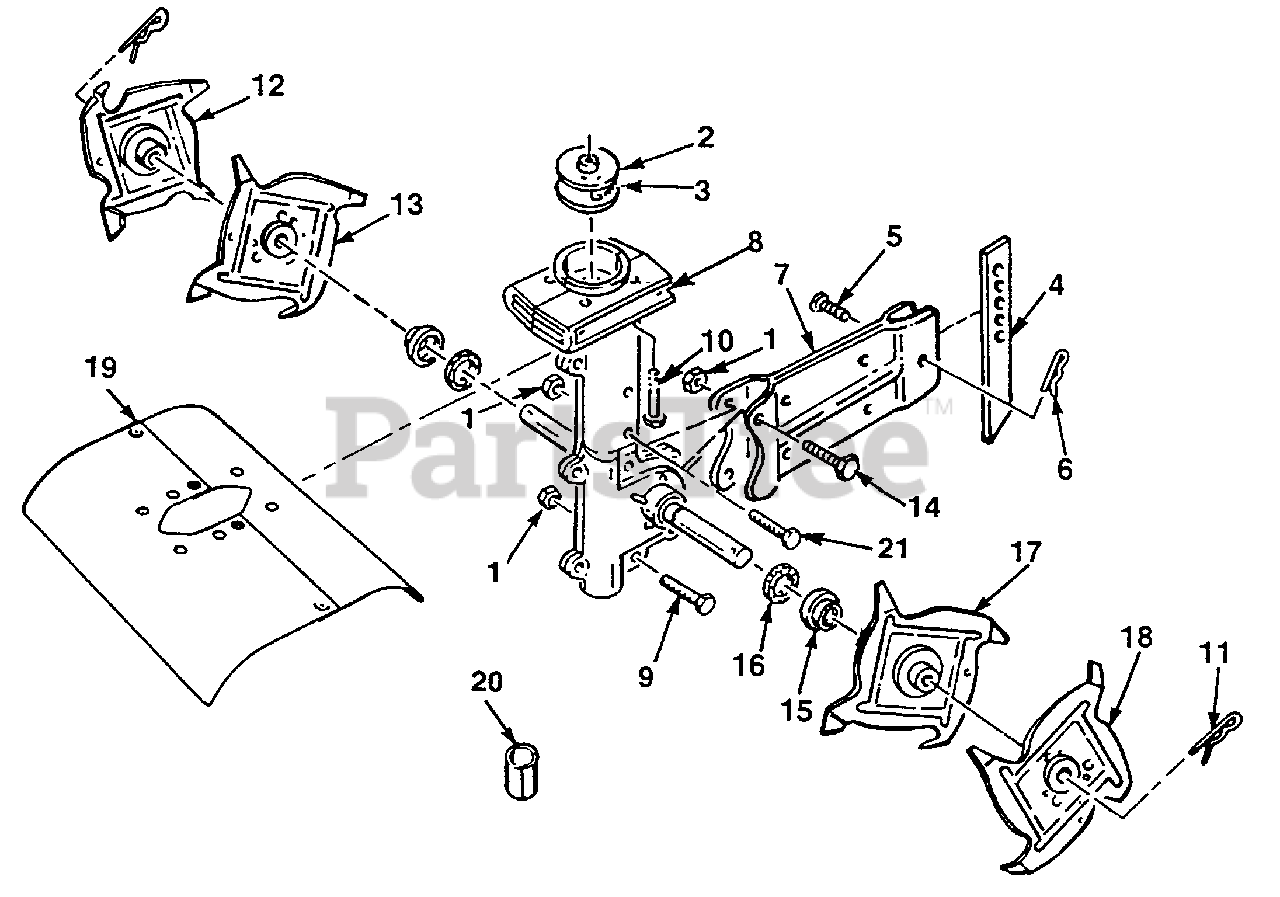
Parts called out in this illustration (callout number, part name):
1	NUT- (1/4-20)
3	SPRING- Clutch
4	DRAG STAKE
5	PIN- Clevis (5/16 x 7/8")
7	DRAG STAKE BRACKET ASSEMBLY
8	TRANSMISSION ASSEMBLY
9	SCREW- Hex hd. (1/4-20 x 3/4")
10	SCREW- Hex washer (10-24 x 2 1/2")
11	HAIRPIN- Cotter (3/4")
12	TINE AND HUB (R.H.) Outboard (D)
13	TINE AND HUB (R.H.) Inboard (C)
14	SCREW- (1/4-20 x 1")
15	DIRT CAP- Black Plastic
16	WASHER- Felt (1/8 x 3/4 x 1 1/2")
17	TINE AND HUB (L.H.) Inboard (B)
18	TINE AND HUB (L.H.) Outboard (A)
19	SHIELD ASSEMBLY
20	TINE SPACERS
21	SCREW- Hex hd. (1/4-20 x 1 1/4")
